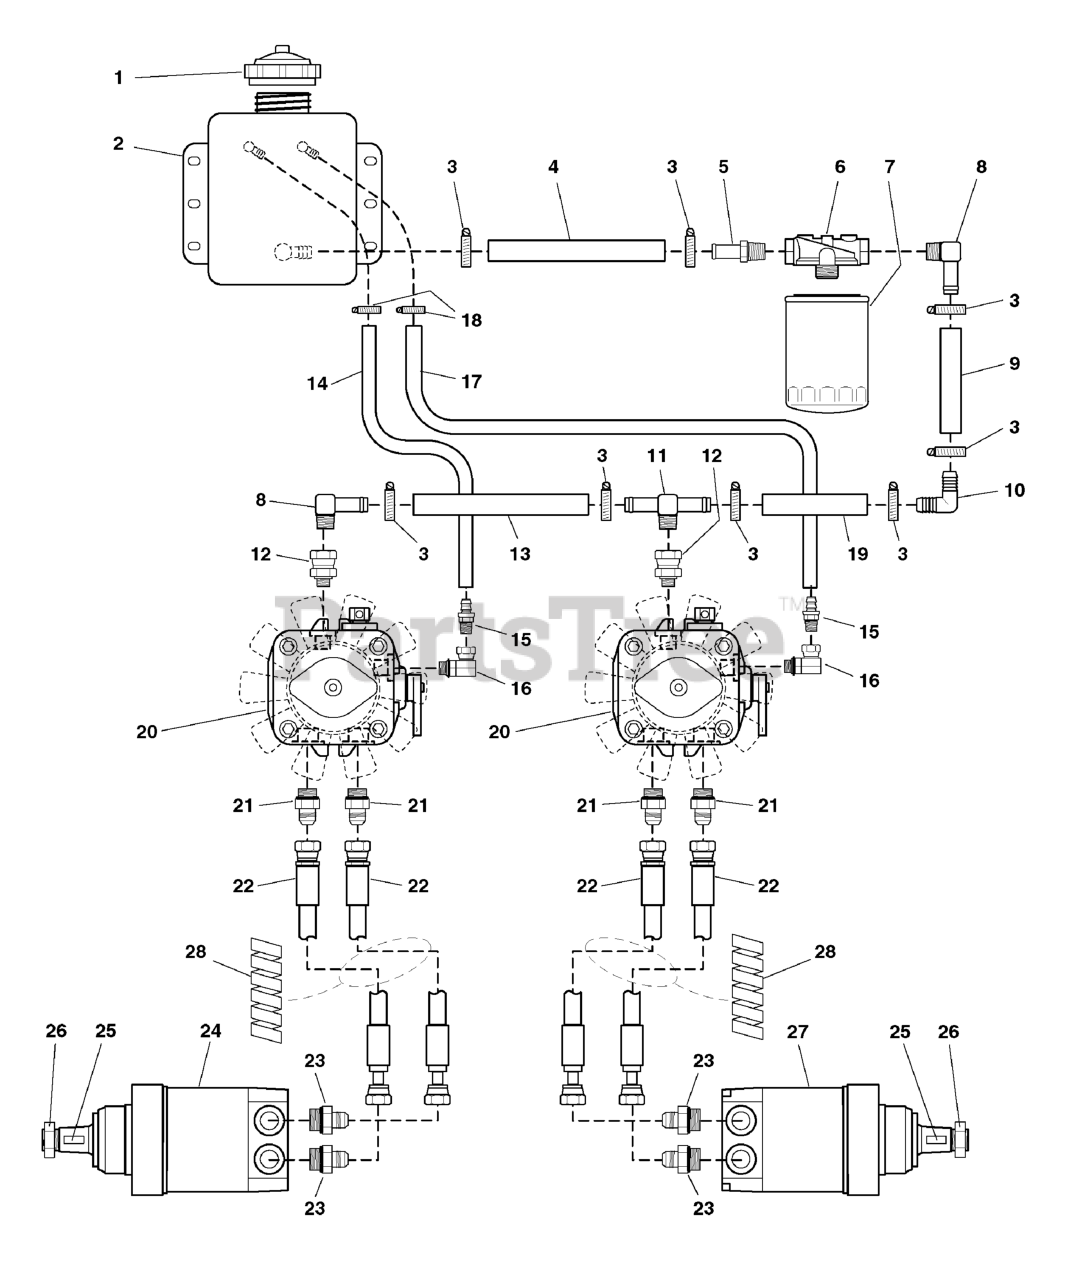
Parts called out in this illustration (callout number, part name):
1	CAP, Fuel Tank
2	KIT, TANK HYDRAULIC, 3QT W/ FITTINGS
3	CLAMP, #10 Hose
4	HOSE, Hydraulic, 11"
5	FITTING, 1/2" NPT, Straight
6	FILTER HEAD
7	FILTER, HYDRAULIC, SERVICE PART (PKG)
8	FITTING, 1/2" NPT, 90 Deg.
9	HOSE, Hydraulic, 3-1/2"
10	FITTING, 5/8", 90 Deg.
11	FITTING, 1/2" NPT, Tee
12	FITTING, Straight Swivel
13	HOSE, Hydraulic, 12"
14	HOSE, Hydraulic, 16"
15	FITTING, 1/4" NPT, Straight
16	FITTING, 9/16 O-RING - 1/4 NPT, 90 DEG
17	HOSE, Hydraulic, 24"
18	CLAMP, #6 Hose
19	HOSE, Hydraulic, 3"
20	HYDRAULIC PUMP, 10CC, w/ FAN
20	HUB & FAN KIT
21	FITTING, O-Ring Adapter
22	HOSE ASSEMBLY, (33)
23	FITTING, O-Ring Adapter
24	HYDRAULIC WHEEL MOTOR-LEFT, Complete
25	KEY
26	NUT & COTTER PIN
27	HYDRAULIC WHEEL MOTOR-RIGHT, Complete
28	PROTECTIVE COIL, 12"
